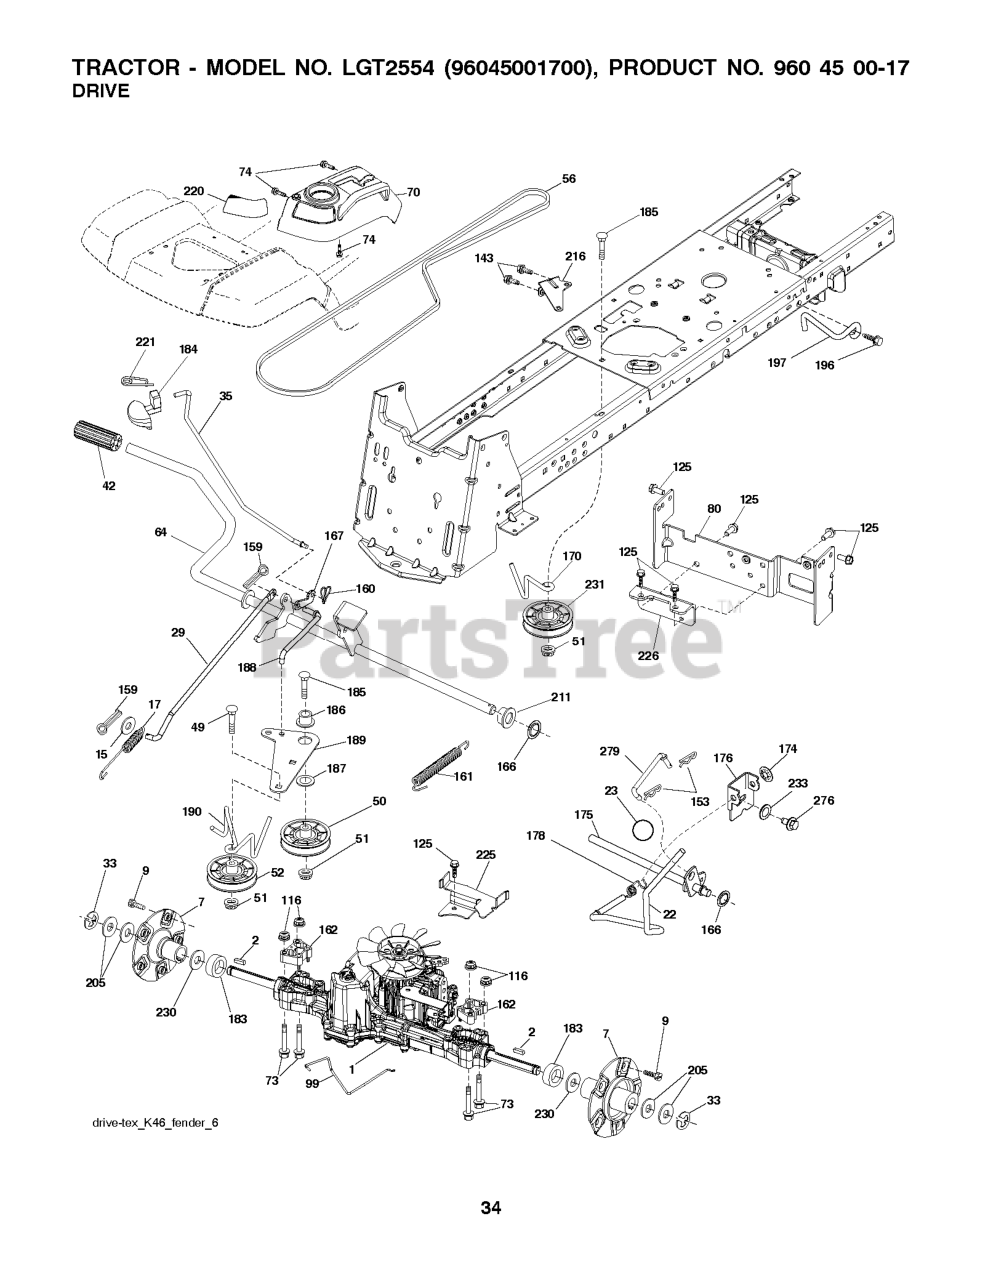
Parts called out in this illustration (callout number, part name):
1	TRANSAXLE(K46AW)22"FS
2	KEY.SQUARE.187X2.500
7	HUB.ASM.WHEEL.REAR.22"
9	HUB BOLT
15	WASHER
17	SPRING.BRAKE.K46.GREEN
22	ROD.SHIFT.FENDER.STGT.
23	KNOB.DELUXE.(PISTOL.GRIP).BLAC
29	ROD.BRAKE.K46
35	ROD.BRAKE.PARKING.GT.H
42	PEDAL COVER T
50	IDLER.FLAT.910.OFFSET
51	NUT LOCK FLG 3/8-16 UNC
52	IDLER.V-GROOVE.910.OFFSET
56	V-BELT.MOWER.92.40.42/K46
64	SHAFT.ASM.PEDAL.BRAKE.
70	RP CONSOLE.ASM.HYDO.HUSQ.
73	BOLT.HEX.FLNG.5/16-18X3.75
74	SCREW.HI-LO.CONSOLE
80	STRAP TORQUE
99	ROD.SPRING.BYPASS.K46.TEX.GT
116	NUT LOCK HEX FLANGE 5/16-18
125	SCREW
143	Screw 5/16-18 x 1/2 Hex, Self Tapping 5/16-18 x 1/2
153	RETAINER M
159	COTTER PIN
160	RETAINER CLIP
161	SPRING, RETURN LT
162	SPACER.TRANSAXLE.18&22
166	NUT.PUSH.625.2006
167	LATCH.BRAKE.SPRING
170	KEEPER.CENTER SPAN.1.688
174	NUT.PUSH.500.2006
175	SHAFT ASM SHIFT
176	ARM.CLEVIS.ROD.SHIFT
178	SPRING.SHIFT.GT2006
183	SPACER.SPLIT.800X.350
184	HANDLE.PARKG.BRK.HUSQ X667
186	SPACER.RETAINER
187	WASHER 12/32X2X10GA
188	RP.LINK.CLUTCH.GROUND.DRIVE
189	BELLCRANK.GROUND.DRIVE.TEX.
190	KEEPER.BELLCRANK.DRIVE
196	SCREW 3/8-16X1
197	BRKT.ANIT-ROTATION.CLUTCH
211	BUSHING.SHAFT.BRAKE.HAND
216	BRACKET.PULLEY.IDLER.W/TEX
220	REFLECTOR.RH.TEX GT
221	RETAINER.SPRING.CLIP.H
225	KEEPER.BELT.TRANSAXLE.K46
226	BRKT.MOUNT.TORQUE.K46.
230	WASHER.HARDENED
231	IDLER.V-GROOVE.1.688.OFFSET
233	WASHER SERRATED
276	BOLT FIN HEX 7/16-14 X 1
279	LINK.SHIFT.T/A.K46.FEND.TX
